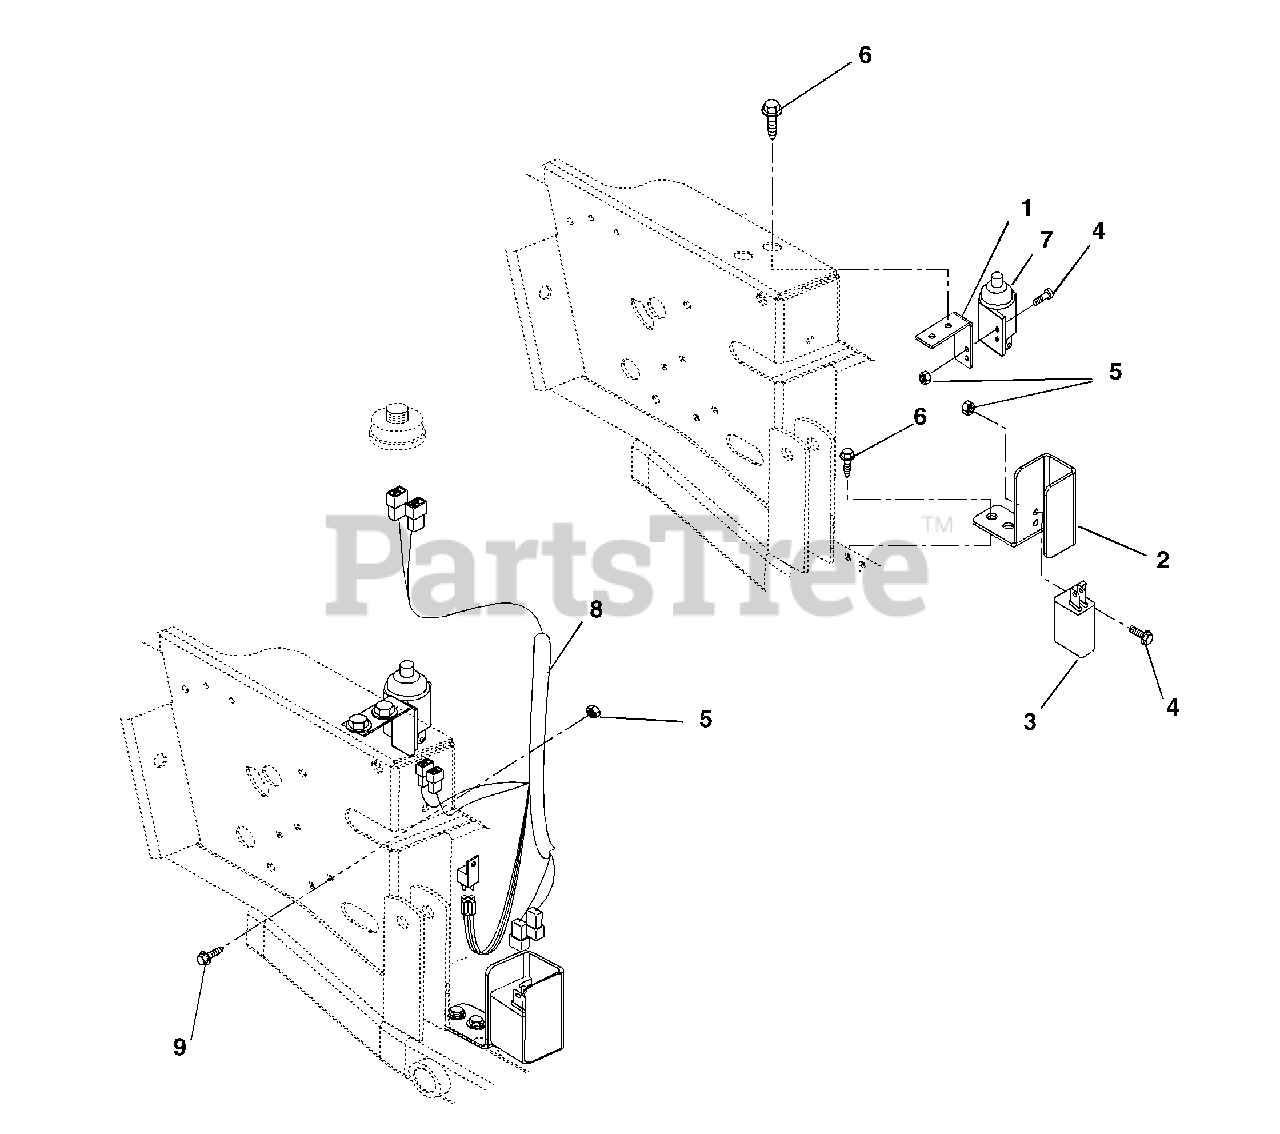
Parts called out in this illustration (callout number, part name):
1	Mount-Switch
2	Bracket-Switch
3	Switch-Single Pole N.O.
4	Screw-Machine 10-24 x .75 Hex Washer Head
5	Nut-Lock-Nylon 10-24 With Insert
6	Screw-Tap .31 x 18 x .50 Hex Washer Head
7	Switch-Single Pole N.O. with Cover
8	Wire Harness-CE Adaptor
9	Screw-Machine 10-24 x .50 Hex Washer Head
